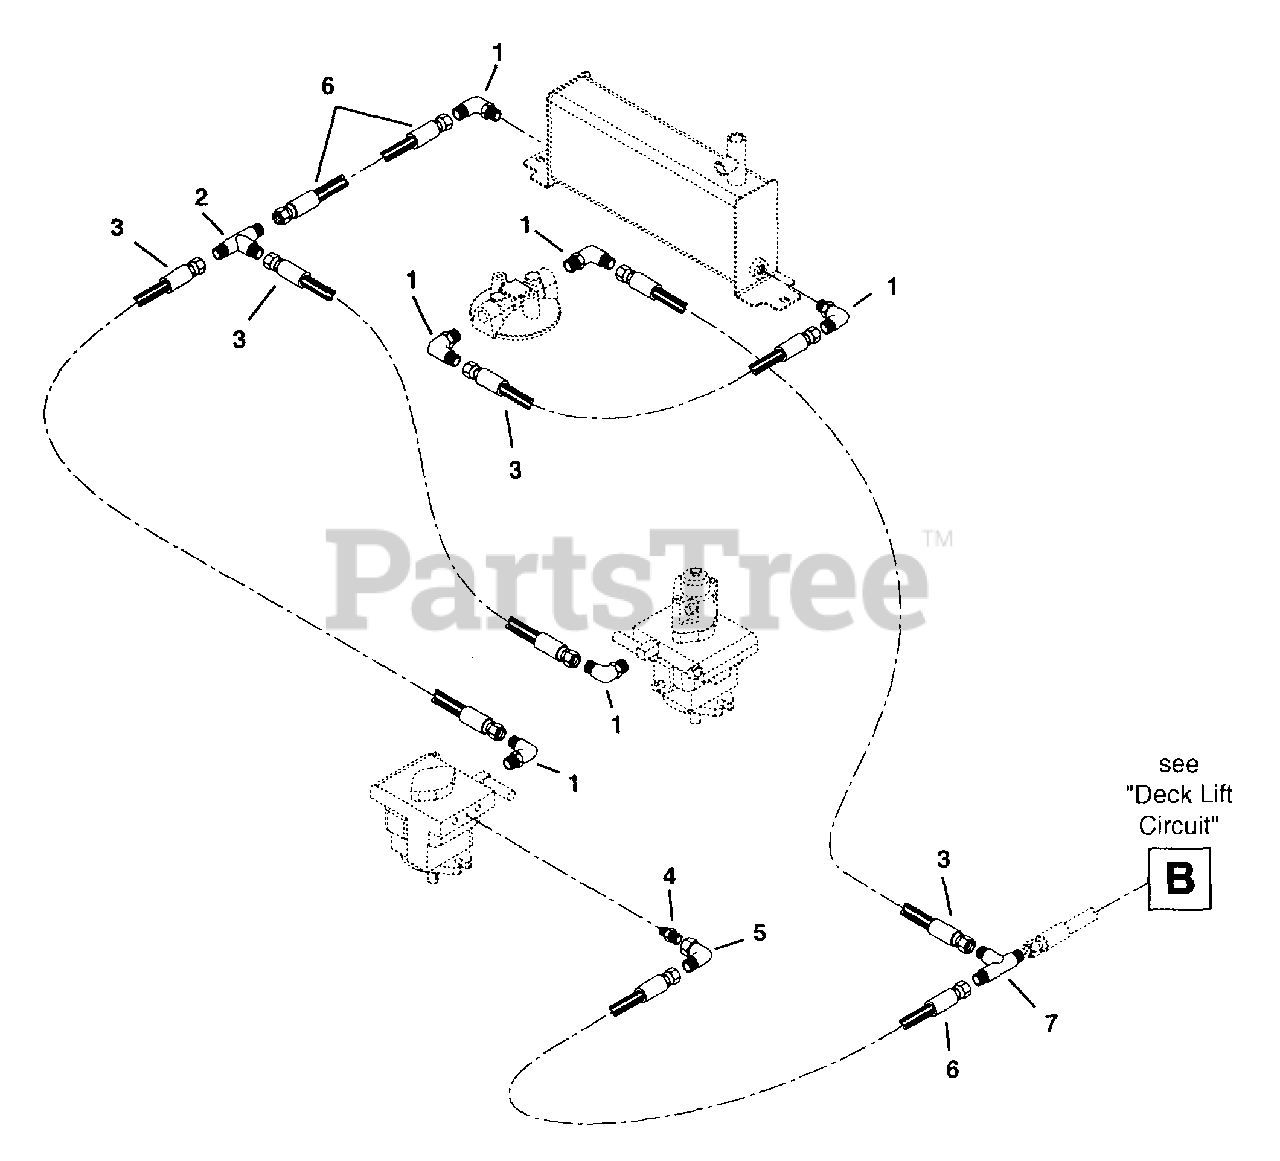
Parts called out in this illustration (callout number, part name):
1	Adapter
2	Adapter-Tee .56-18
3	Hose-Hydraulic Valve to Tank
5	Adapter
6	Hose-Pump to Tee
7	Adapter-Tee .56-18
